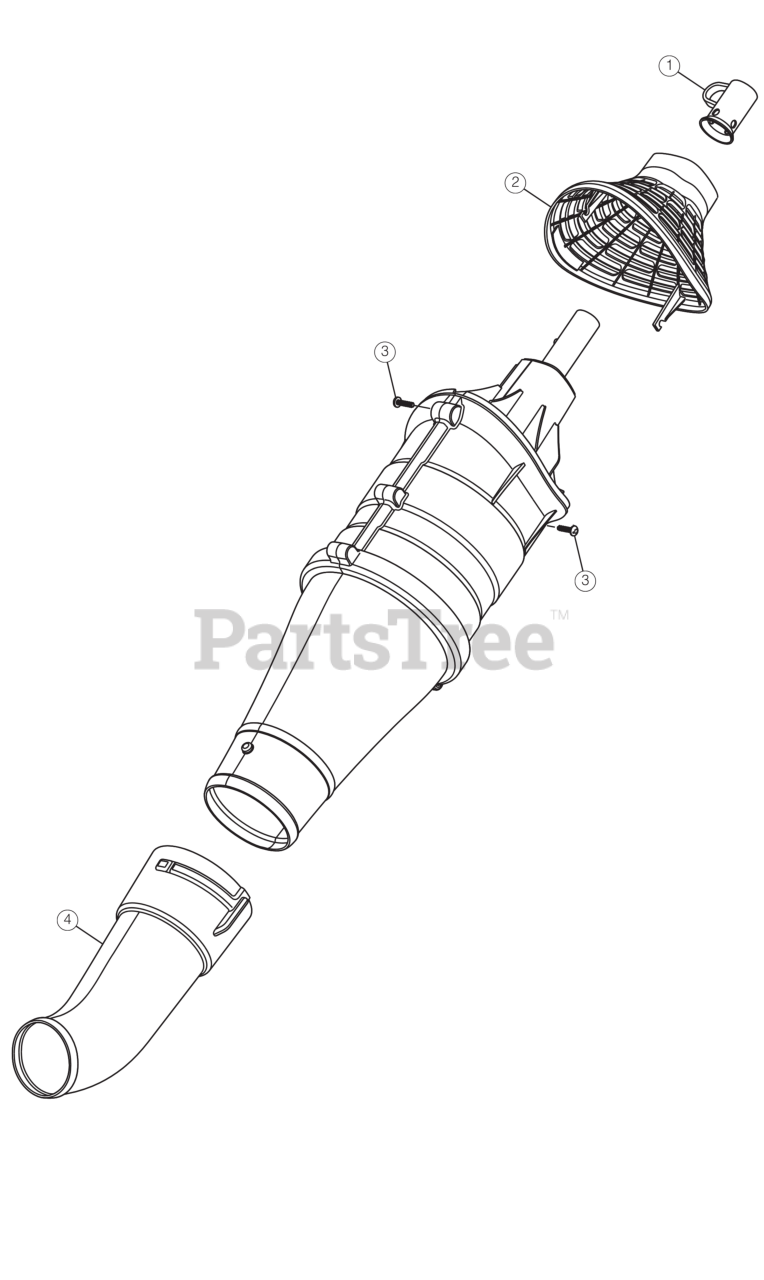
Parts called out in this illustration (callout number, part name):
1	HANGER
2	INTAKE BLOWER ATTACH
3	SCREW 8-16 x 3/4
4	NOZZLE BLOWER ATACH
